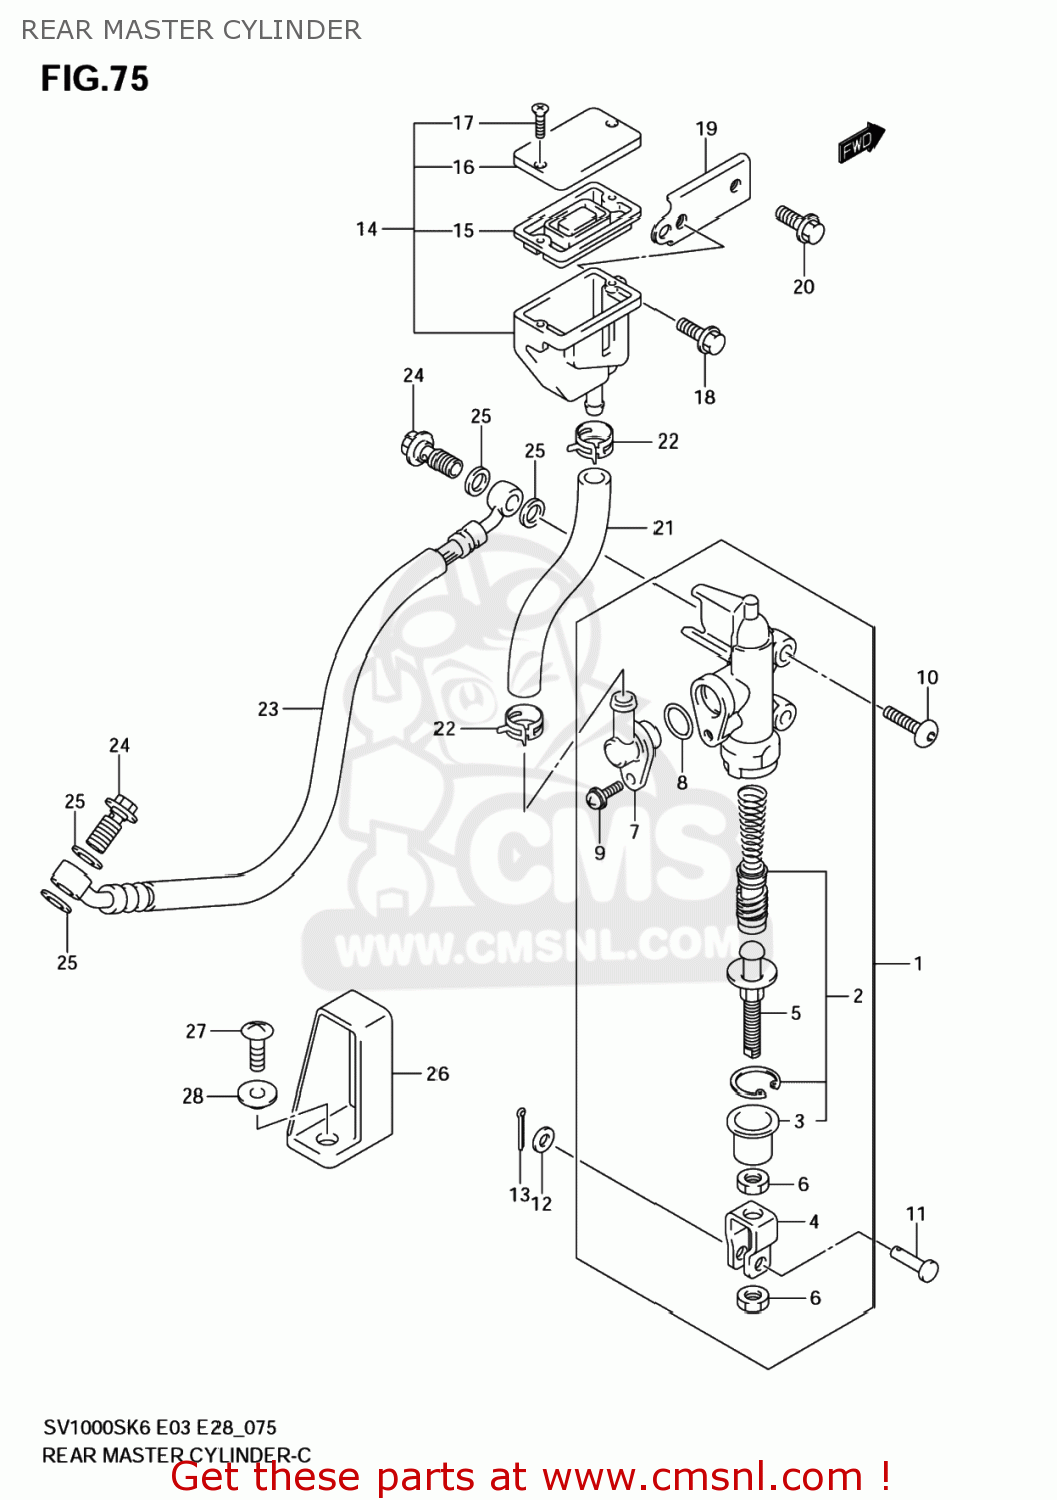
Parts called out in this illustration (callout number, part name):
1	CYLINDER ASSY,RR MASTER
2	PISTON/CUP SET
3	BOOT
4	YOKE
5	ROD,PUSH
6	NUT
7	CONNECTOR
8	O RING
9	SCREW
10	SCREW(6X20)
11	PIN
12	WASHER
13	PIN
14	TANK ASSY,RR RESERVOIR
15	DIAPHRAGM
16	CAP
17	SCREW
18	BOLT(6X12)
19	BRACKET,RR RESERVOIR TANK
20	BOLT
21	HOSE,RR RESERVOIR TANK
22	CLIP
23	HOSE,RR BRAKE
24	BOLT UNION
25	WASHER(10X15X1.5)
26	GUIDE,RR BRAKE HOSE
27	SCREW
28	WASHER
